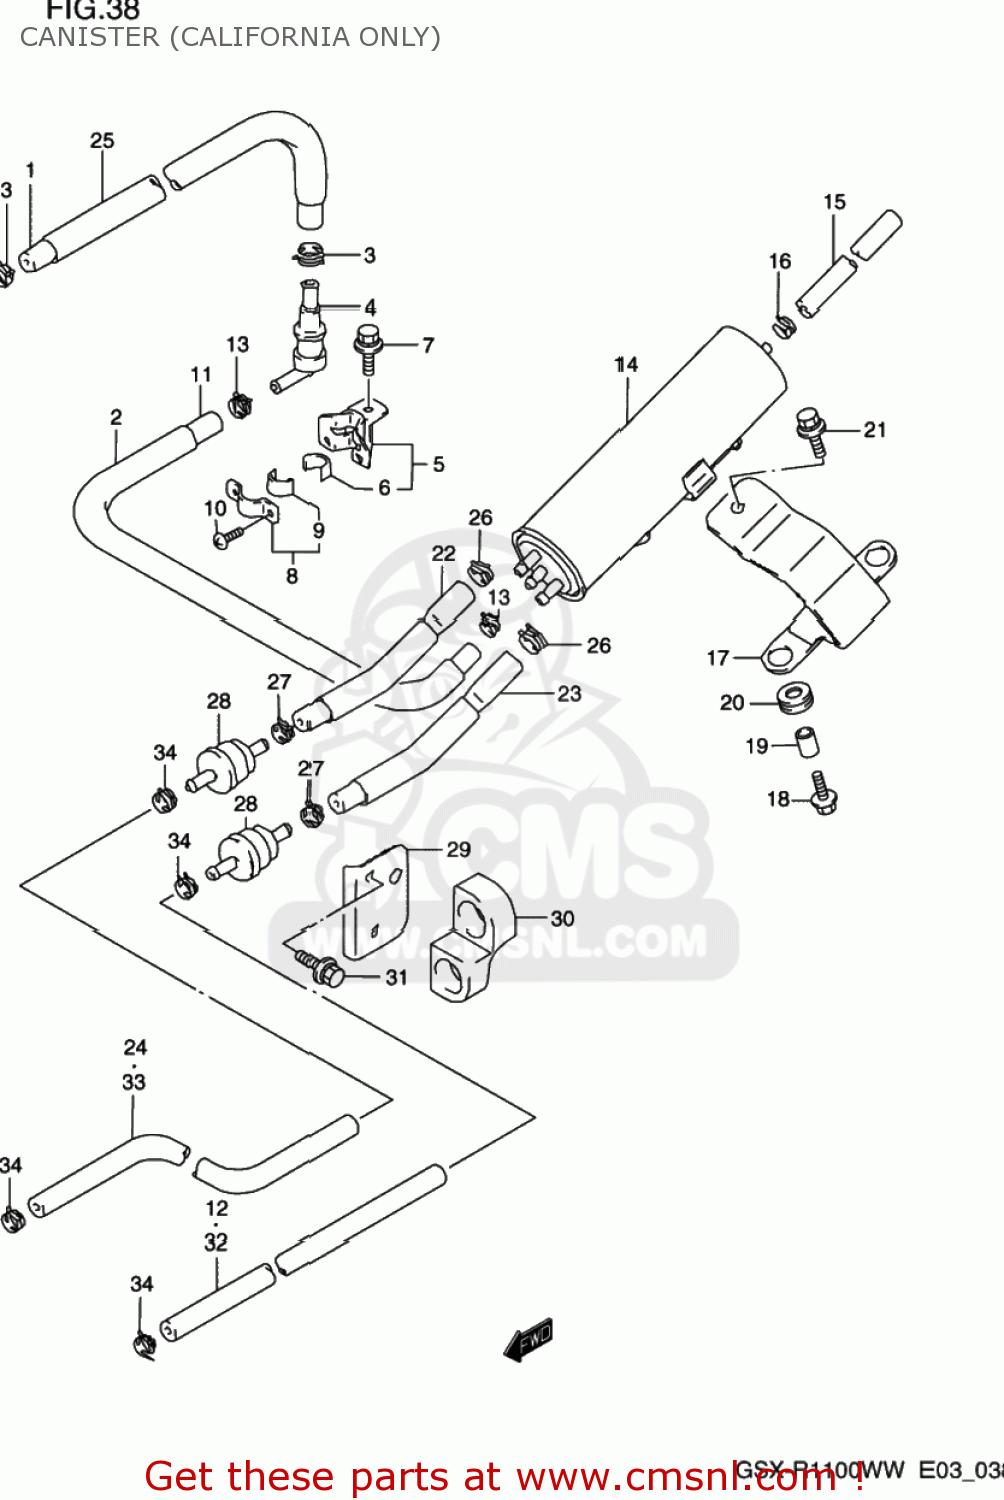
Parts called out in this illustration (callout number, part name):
1	HOSE(5.4X11.4X600)
2	PROTECTOR,FUEL HOSE
3	CLIP
4	VALVE,FUEL TANK BREATHER
5	BRACKET,BREATHER VALVE
6	CUSHION
7	BOLT
8	PLATE,FUEL TANK BREATHER NO.2
9	CUSHION
10	SCREW
11	HOSE(5.4X11.4X600)
12	PROTECTOR,EVAPORATOR HOSE,LEFT
13	CLIP
14	CANISTER ASSEMBLY,CHARCOAL
15	HOSE (7X12X150)
16	CLIP
17	BRACKET,CANISTER
18	BOLT
19	SPACER
20	CUSHION
21	BOLT
22	HOSE(5.4X11.4X600)
23	HOSE(5.4X11.4X600)
24	PROTECTOR,EVAPORATOR HOSE,N
25	PROTECTOR,EVAPORATOR HOSE,N
26	CLIP
27	CLIP
28	VALVE,CANISTER PURGE
29	BRACKET,CANISTER PURGE VALVE
30	(CA) CUSHION,CANISTER P VA
31	BOLT
32	HOSE(5.4X11.4X600)
33	HOSE(5.4X11.4X600)
34	CLIP
